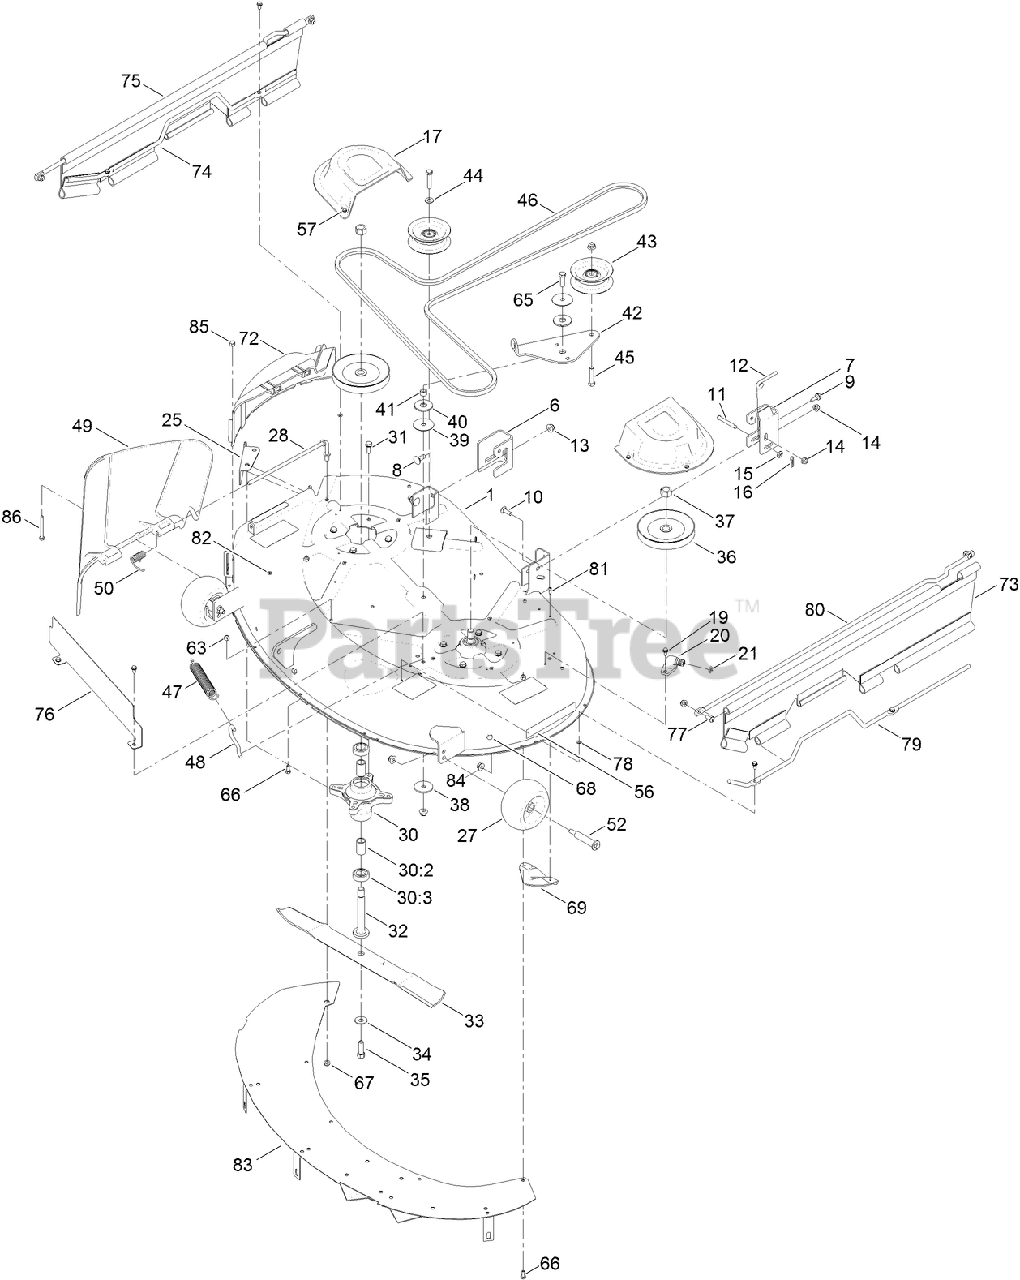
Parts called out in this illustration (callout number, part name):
1	42 INCH DECK AND DECAL ASM
6	BRACKET-HANGER, RH
7	BRACKET-HANGER, LH
8	BOLT-CARR
9	SCREW-SHOULDER,HWH
10	SCREW-CARR
11	PIN-CLEVIS
12	ROD-LEVEL, DECK
13	NUT-HF, NI
14	NUT-HF, NI
15	WASHER-PLAIN
16	PIN-COTTER
17	COVER-BELT
19	SCREW-HWH
21	O-RING
25	BAFFLE-CUTOFF
27	ROLLER-SCALP, ANTI
28	ROD-PIVOT
30	SPINDLE ASM
30:2	SPACER
30:3	BEARING-BALL
31	SCREW-TAPTITE
32	SHAFT-SPINDLE
34	WASHER-BELLEVILLE
35	SCREW-HH
36	PULLEY
37	NUT-HEX
38	WASHER-REBOUND
39	WASHER
40	WASHER-FRICTION, COMPOSITE
41	SPACER
42	ARM-IDLER
44	WASHER-FLAT
45	SCREW-HH
46	V-BELT
47	SPRING-EXTENSION
48	HOOK-RETURN, SPRING
49	DEFLECTOR
50	SPRING-TORSION
52	BOLT-SHOULDER
56	DECAL-RECYCLER
57	SCREW-TAPTITE
63	NUT-LOCK, NI
65	SCREW-HH
66	SCREW-HH
68	SCREW-HH
69	PLATE-KICKER
72	COVER-DISCHARGE
73	ROD-SUPPORT, UPPER
74	ROD-SUPPORT, LOWER (RH)
75	RH GUARD SIDE
76	SHIELD-FRONT, DECK
77	SCREW-HSBH
78	NUT-RETAINING
79	ROD-SUPPORT, LOWER (LH)
80	GUARD-SIDE, LH
81	SCREW-PPH
82	NUT-RETAINING
83	BAFFLE UPPER ASM
84	NUT-HF
85	NUT-CAP
86	SCREW-HH
